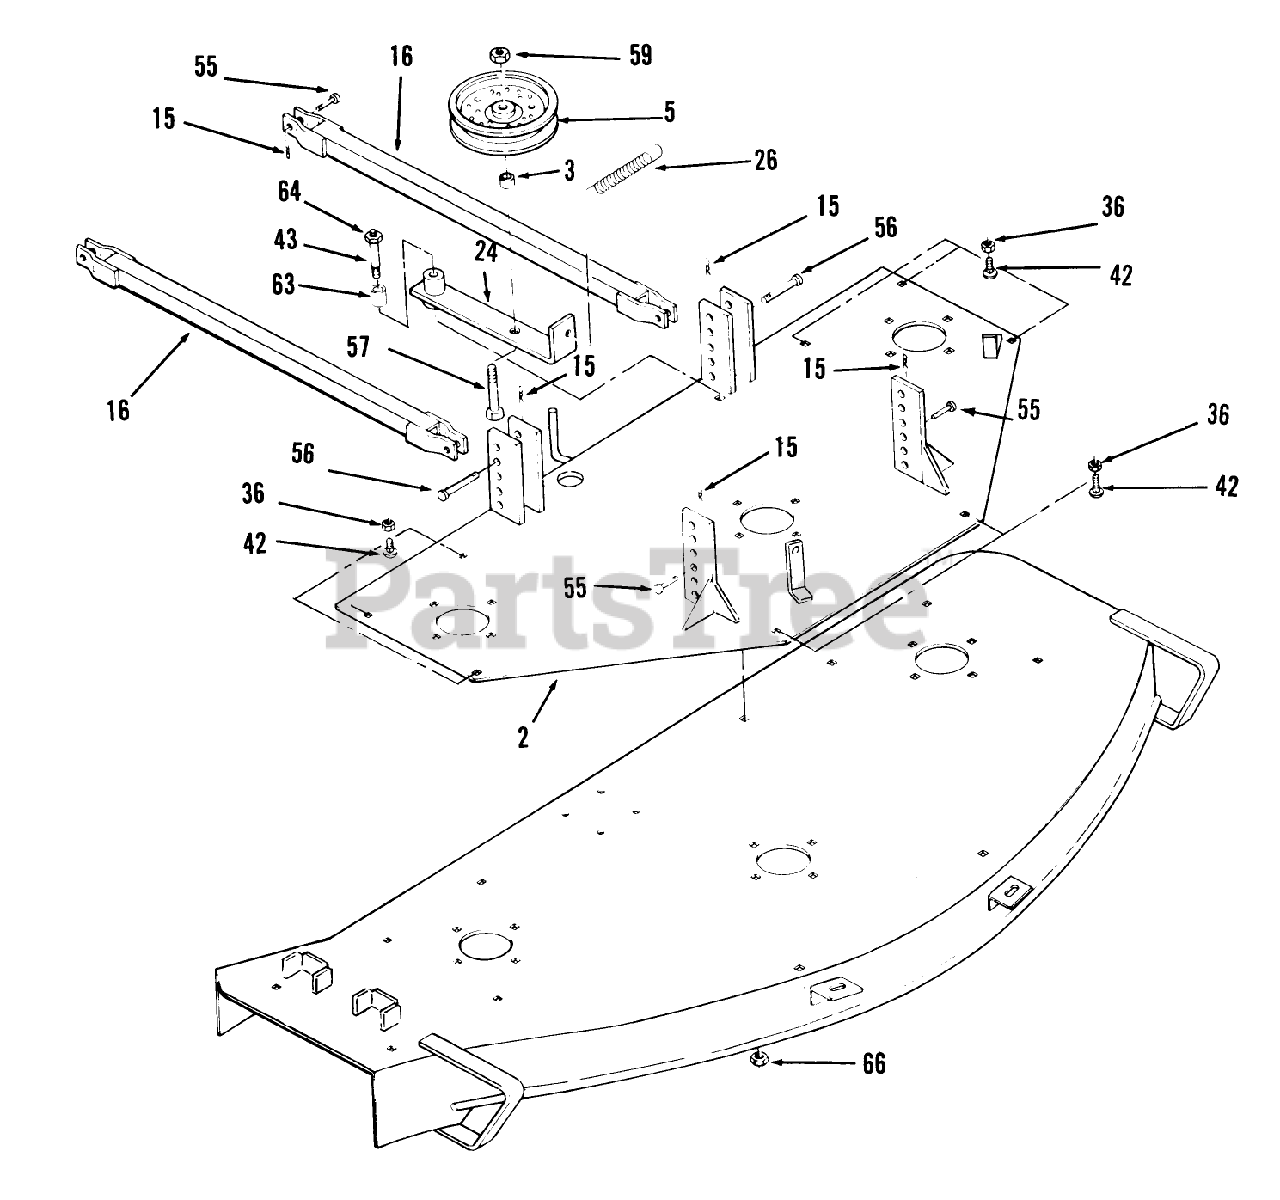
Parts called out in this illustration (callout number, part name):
2	ASS'Y-MWR DECK PL R
3	SPACER
5	PULLEY FLAT B
15	HAIRPIN
16	Bar-Stabilizer
24	ASS'Y-IDLER ARM R
26	SPRING-EXTENSION
36	NUT-LOCK, NI
42	Carriage Bolt 5/16-18 x 3/4-50" Mower Only
42	BOLT-CARR
43	BOLT-SHOULDER
55	Clevis Pin 3/8 x 1 1/4
56	Clevis Pin 3/8 x 2-1/4
57	SCREW-HH
59	NUT-LOCK, NI
64	FITTING-GREASE, 90 DEG
66	NUT-LOCK, NI
